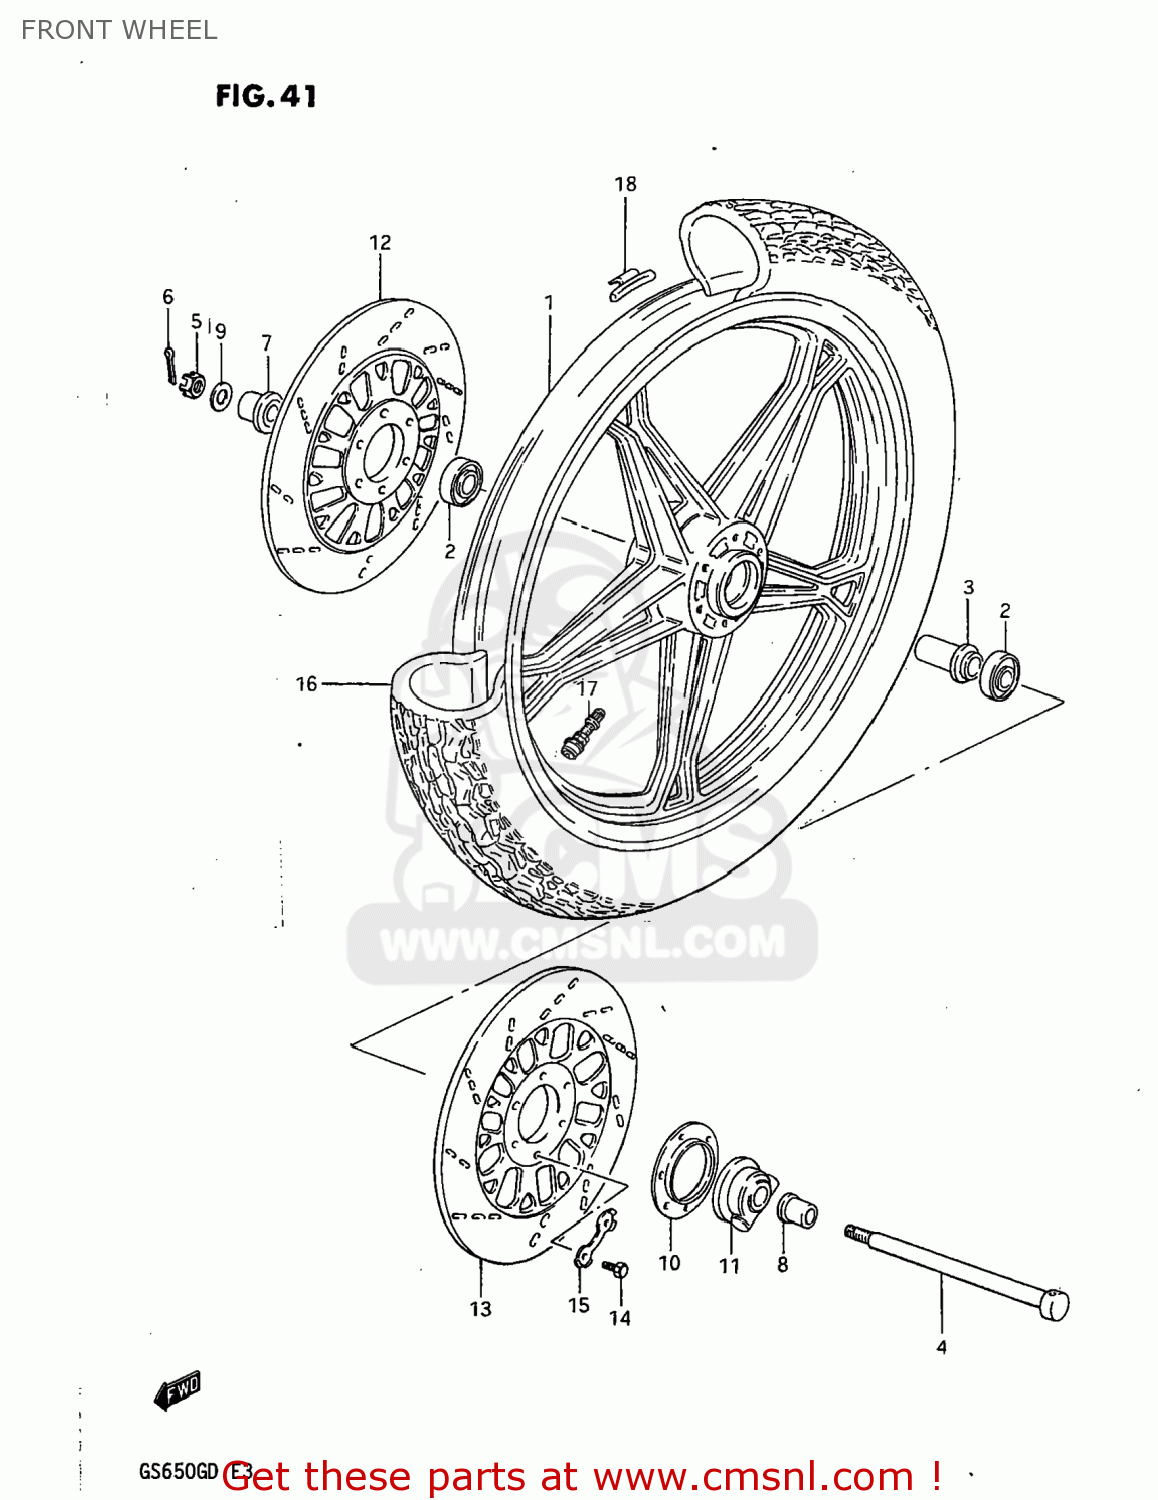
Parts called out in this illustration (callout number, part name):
1	CASTING WHEEL,FRONT 1.85
2	BEARING
3	SPACER,FR HUB BEARING
4	AXLE,FRONT
5	NUT 12MM
6	COTTER PIN
7	SPACER,FR HUB BEARING,R
8	SPACER(15X22X30)
9	WASHER
10	DUST SEAL,SPEEDOMETER GEAR BOX
11	BOX ASSEMBLY,SPEEDOMETER GEAR
12	DISC,FR BRAKE,R
13	DISC,FR BRAKE,L
14	BOLT(8X25)
15	WASHER
16	TIRE,FRONT
17	VALVE ASSEMBLY,WHEEL RIM,J
18	BALANCER,WHEEL
